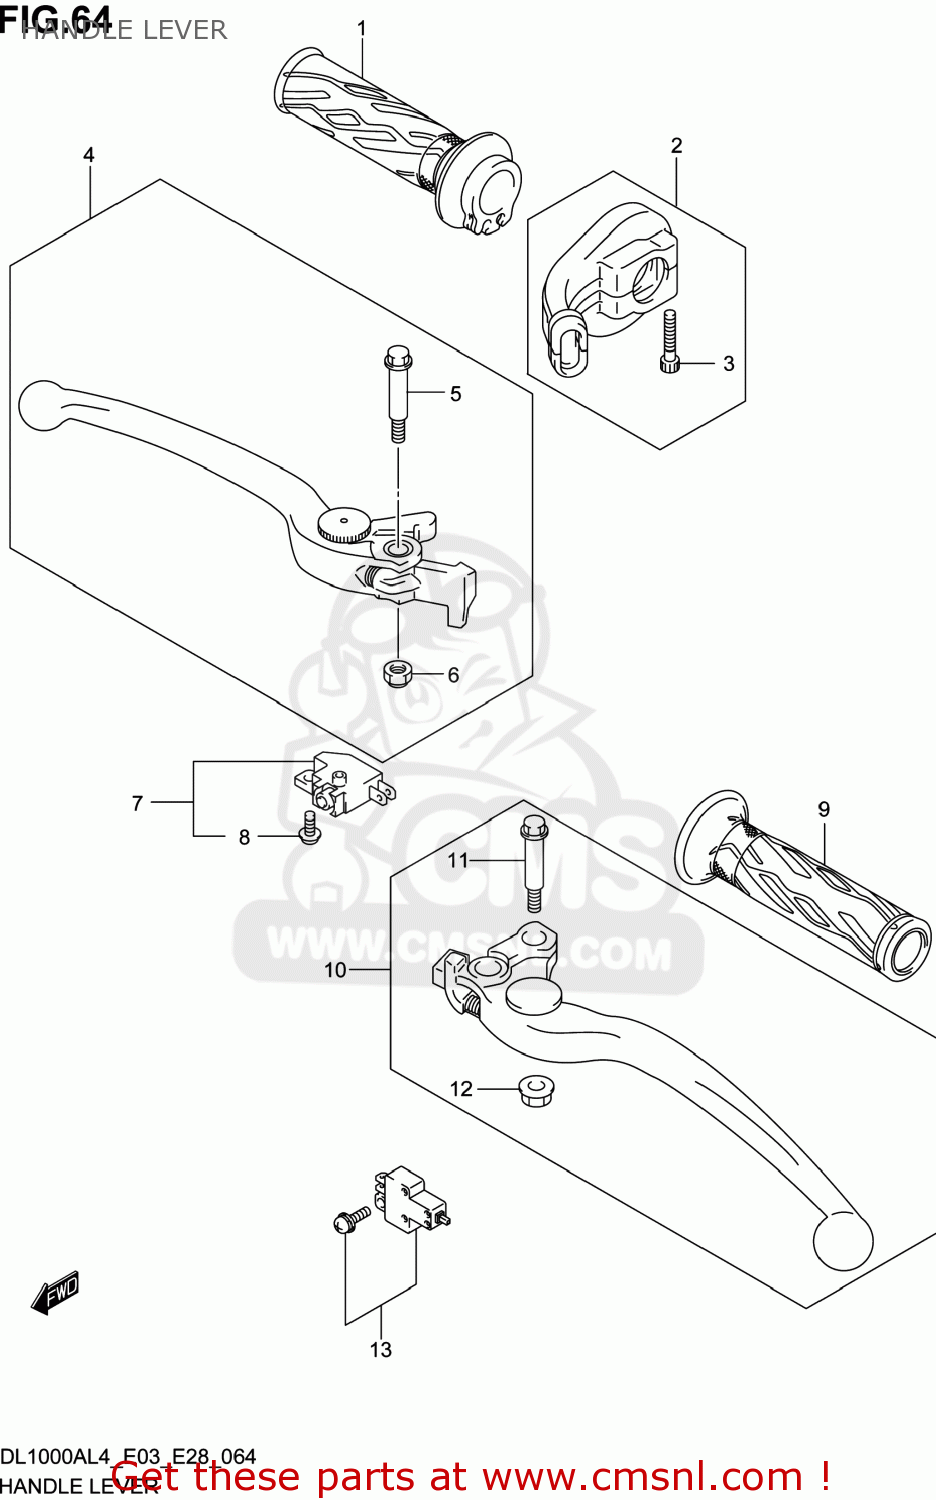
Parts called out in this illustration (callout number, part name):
1	GRIP,THROTTLE
2	CASE ASSY,THROTTLE
3	BOLT
4	LEVER ASSY,BRAKE
5	BOLT,LEVER PIVOT
6	NUT
7	SWITCH ASSY,FR BRAKE
8	SCREW
9	GRIP,L
10	LEVER ASSY,CLUTCH
11	BOLT,LEVER PIVOT
12	NUT
13	SWITCH ASSY,CLUTCH
